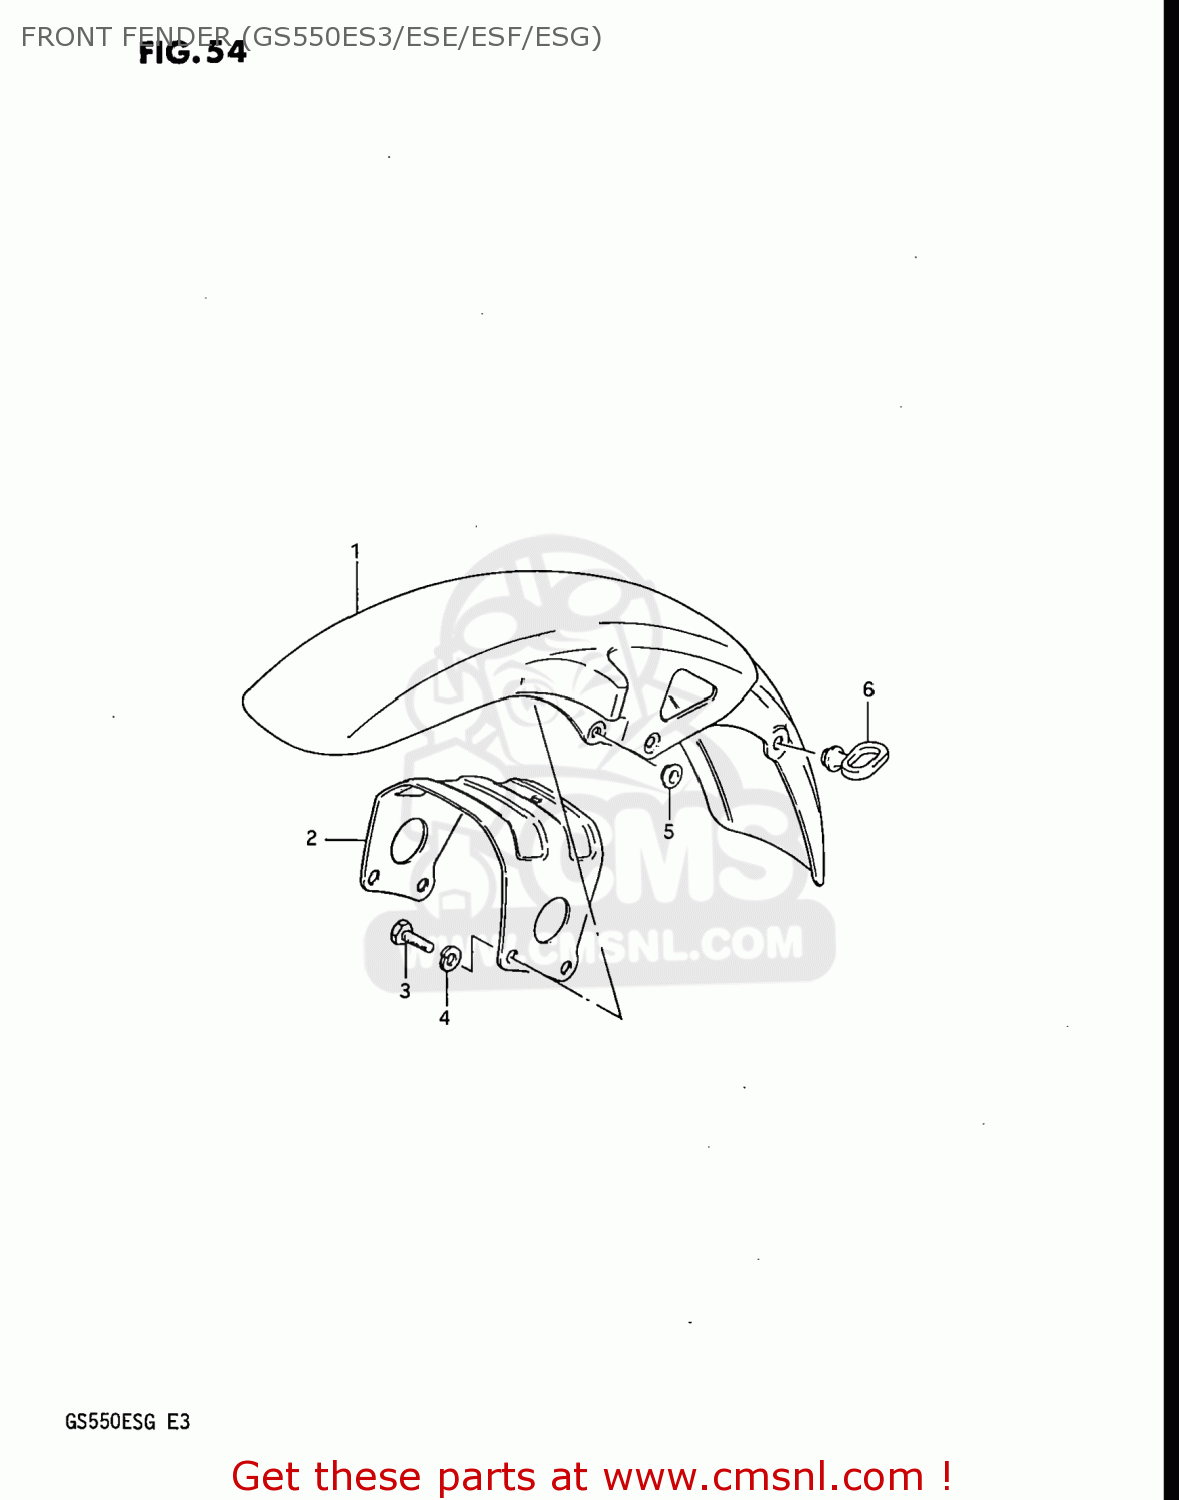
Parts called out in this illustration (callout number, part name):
1	FENDER,FRONT
2	BRACE,FRONT FENDER
3	BOLT
4	LOCK WASHER
5	WASHER
6	GUIDE,CABLE
